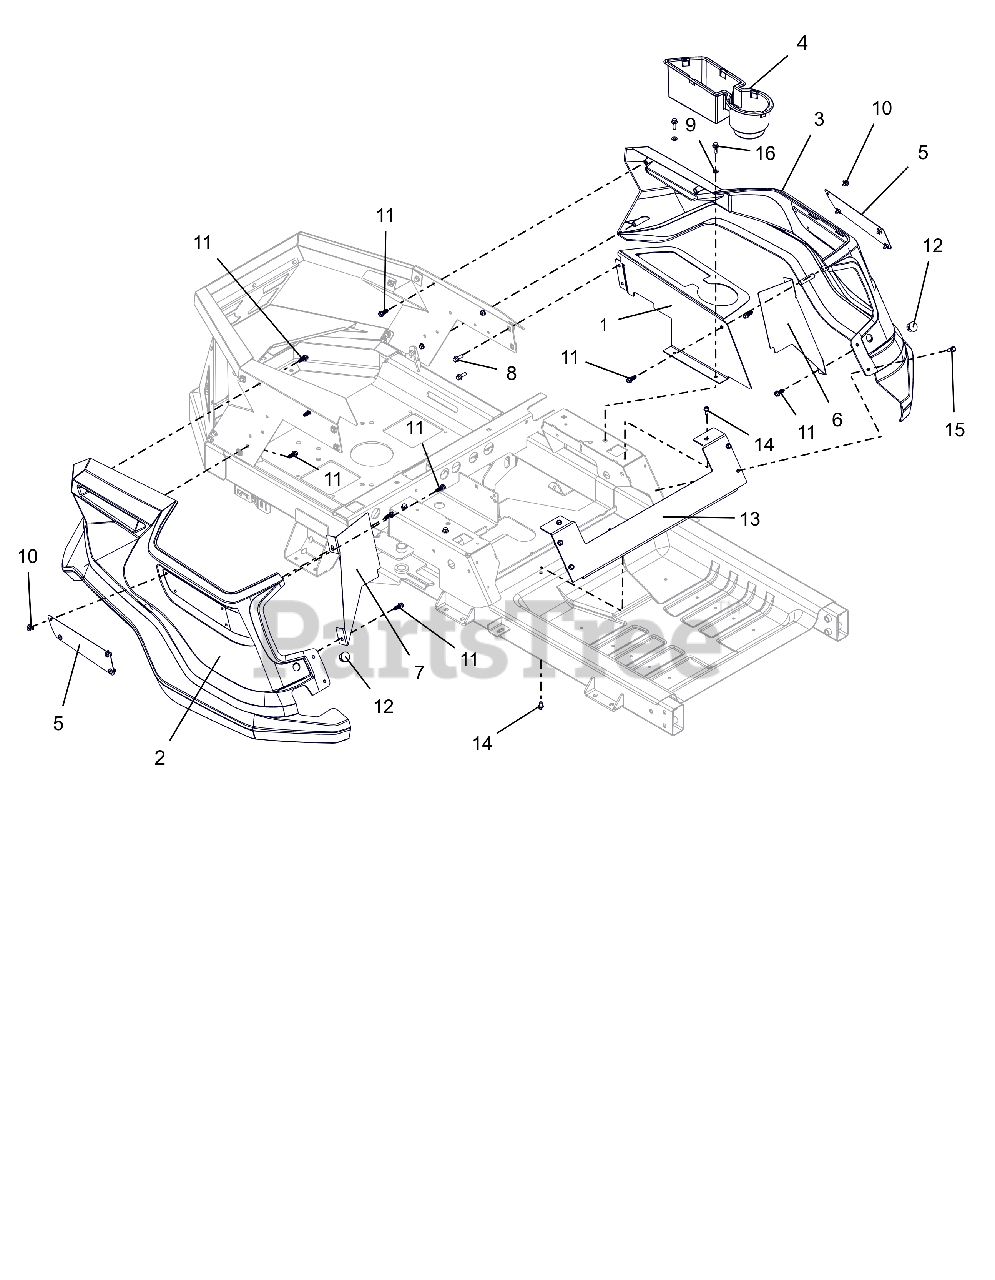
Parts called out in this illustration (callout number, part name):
1	PANEL, LEFT SIDE FENDER MOUNT
2	FENDER, RH IKON
3	FENDER, LH IKON
4	INSERT, CUP/STORAGE HOLDER
5	PLATE, ARIENS NAME
6	PLATE, LH BLOCKER
7	PLATE, RH BLOCKER
8	BLT,HEX-FLG .25-20X.75 G5 BFP
9	@WSHR-LK .25X.062 REG YWZC
10	RIVET, PLASTIC .195 DIA.
11	SCR-.312X.75 #14H H/W/H H/L CZ
12	PLUG, HOLE .75 (BLACK)
13	PLATE, SEAT KICK
14	SCR-TAP .25-20X.50 HWH TR YWZ
15	SCR-TAP-PM .25-20X.75 TR YWZ
16	BLT,HEX-FLG .25-20X.75 G5 BFP
